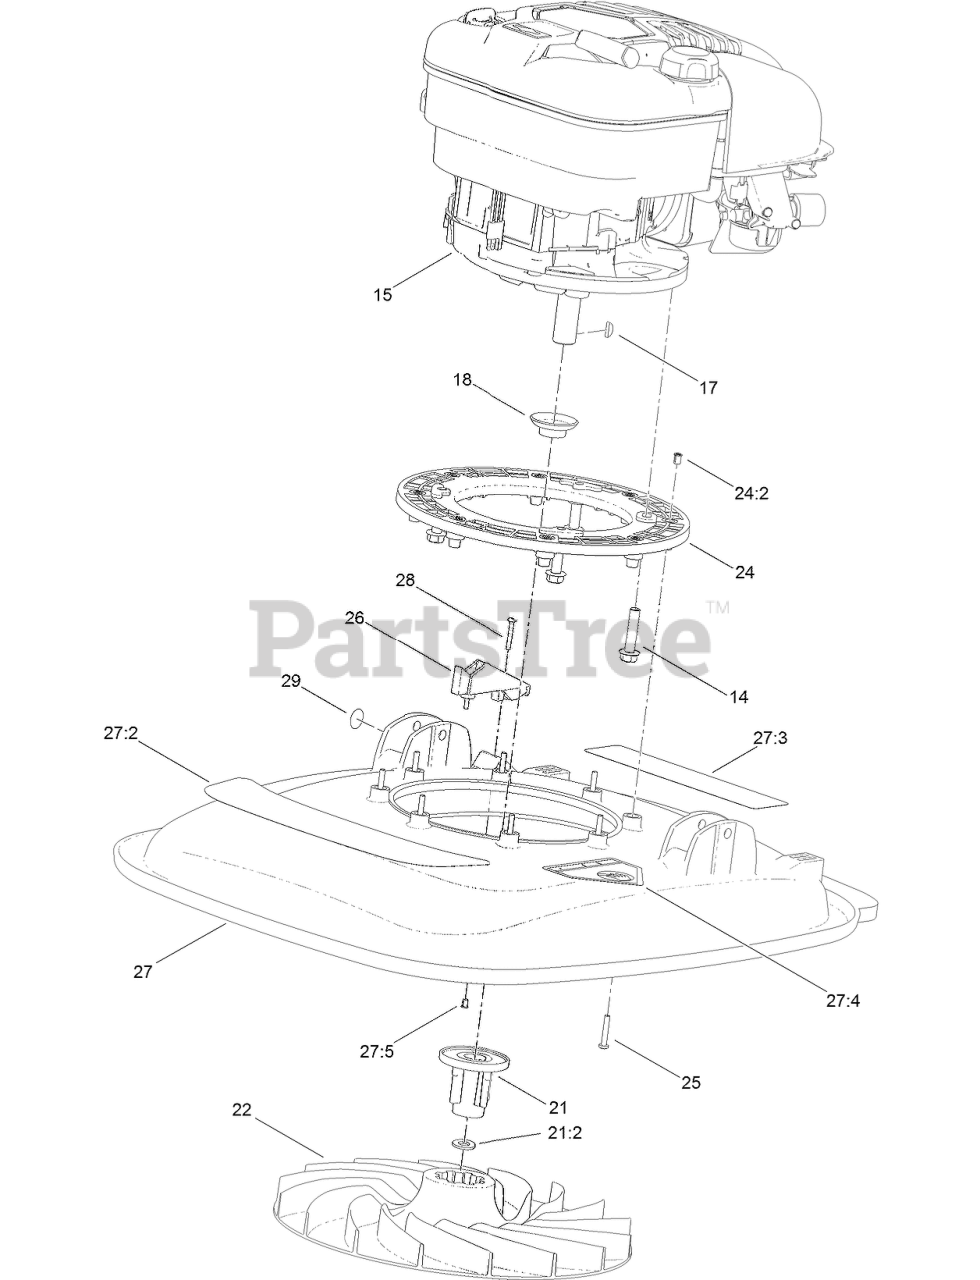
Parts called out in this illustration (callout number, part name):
14	SCREW-TAPTITE
15	ENGINE-Honda
17	KEY-WOODRUFF
18	PROTECTOR-SEAL, OIL
21	DRIVE AND SPACER ASM
21:2	WASHER-PLAIN
22	IMPELLER
24	FRAME-ENGINE
24:2	INSERT-BRASS
25	SET-SCREW
26	BRACKET
27	DECK ASM
27:2	DECAL-HOVER PRO
27:3	DECAL-WARNING
27:4	DECAL-DANGER
27:5	INSERT
28	SCREW
29	DECAL
